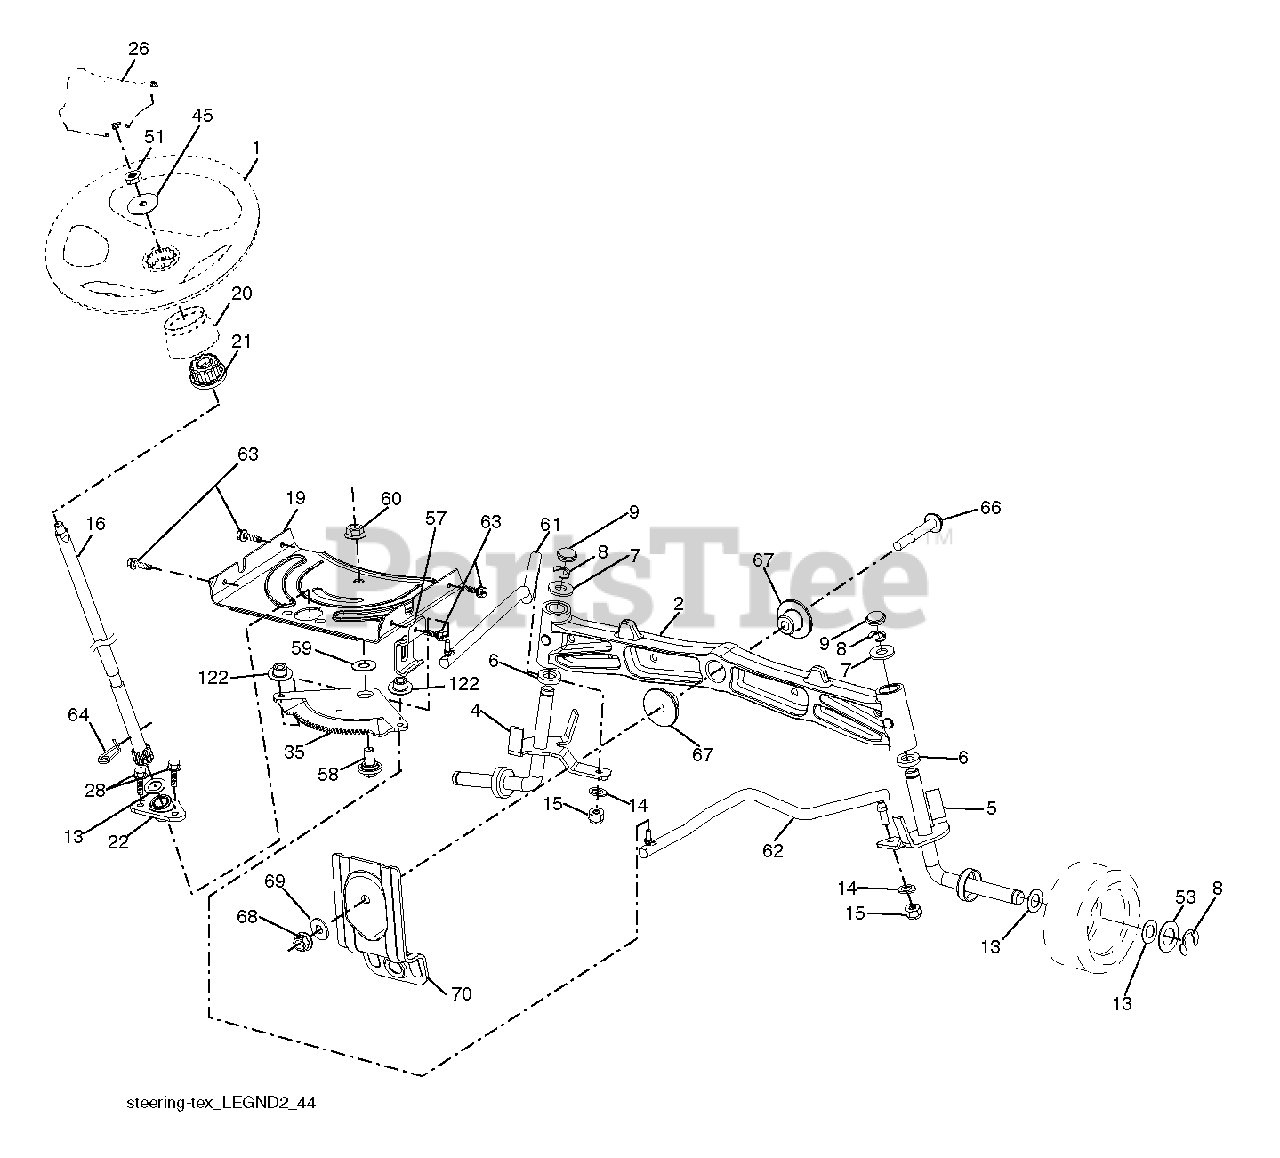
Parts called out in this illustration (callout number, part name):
1	WHEEL.STEERING.STDSRR.BLK/OV
2	AXLE.CAST.IRON
4	SPINDLE.WELDED.LH.16"TEX
5	SPINDLE.WELDED.RH.16"TEX
8	RING CLIP
9	CAP.SPINDLE
14	WASHER, LOCK 3/8
15	NUT CROWNLOCK 3/8-24
16	SHAFT, STEERING
19	PLATE.STEER.DDL.NLT/NG
20	BOOT.STEERING.
21	ADAPTER, WHEEL STNG..
22	STEERING.SUPT.LOWER.
26	CAP.WHL.STRNG.STDSRRD.SRS.BLK
28	SCREW, 3/8-16X3/4
35	GEAR.SECTOR.PLATE.DDL.
45	WASHER 9/16"ID, 2 3/8"OD
51	NUT.HEX.1/2-20
53	WASHER.HARDENED
57	BRKT.UPSTOP.GT/LT.TEX
58	BOLT.SHOULDER.SECTOR.P
59	WASHER.THURST.SECTOR.S
60	NUT FLANGE LOCK 5/8-11
61	DRAGLINK.LH.BALLSTUD.D
62	DRAGLINK.RH.BALLSTUD.D
63	SCREW
64	RETAINER.CLIP.SPRING.S
66	BOLT HEX FGHD 7/16-14 X 3 SERR
67	BUSHING.PM.FRONT AXLE
68	NUT.LOCK.FLANGE.7/16
69	WASHER.1.5X.505X.118
70	BRKT.DECK.SUSPENSION.F
